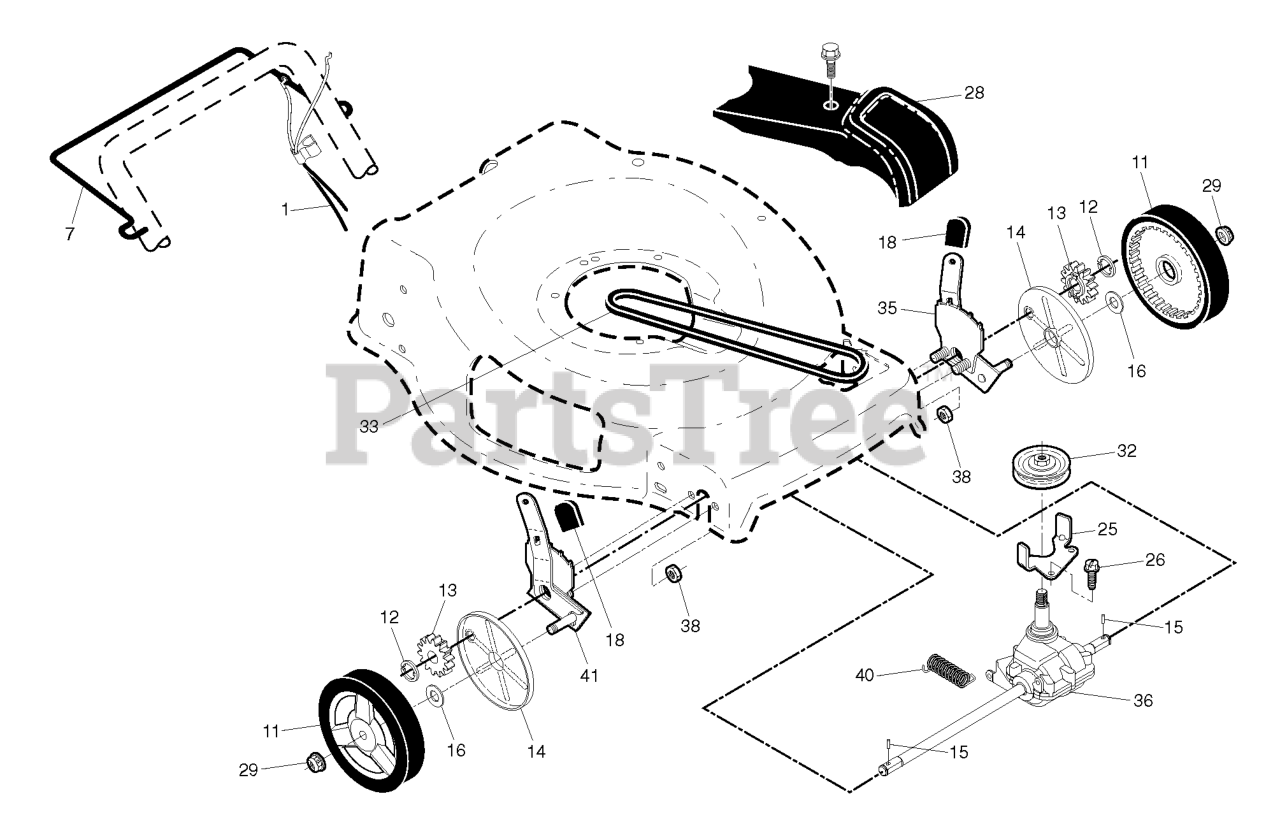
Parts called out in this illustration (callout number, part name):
1	CABLE.DRIVE.VS/SS.22+FGD.MCCUL
7	BAIL.CURVED.UNDER.BAIL.BLACK
11	WHEEL.8X1.75.H3SPK.RAD3.GY.BU3
12	E-RING 7/16 RE
13	PINION.14.TEETH.FGD
14	COVER.DUST.WHEEL.INNER.WALK
15	PAWL, DRIVE
16	WASHER FLUT
18	SELECTOR KNOB
25	BRACKET.BELT.GUIDE.22+FGD.BZP
28	COVER.DR.ASM.421097.HUSQ.CE
29	NUT.HEX.FLANGE.3/8-16.LO(3 2)
32	PULLEY.DRIVEN.EZ/VARI (2 2MC)
33	BELT.DRIVE.FGD.
35	ADJUSTER.ASM.22+FGD.LF /AWD LT
36	TRANSMISSION.22+.FWGD.SS/VS
38	NUT.FLANGE.1-4-20-SERR
41	ADJUSTER.ASM.22+FGD.RF /AWD RT
